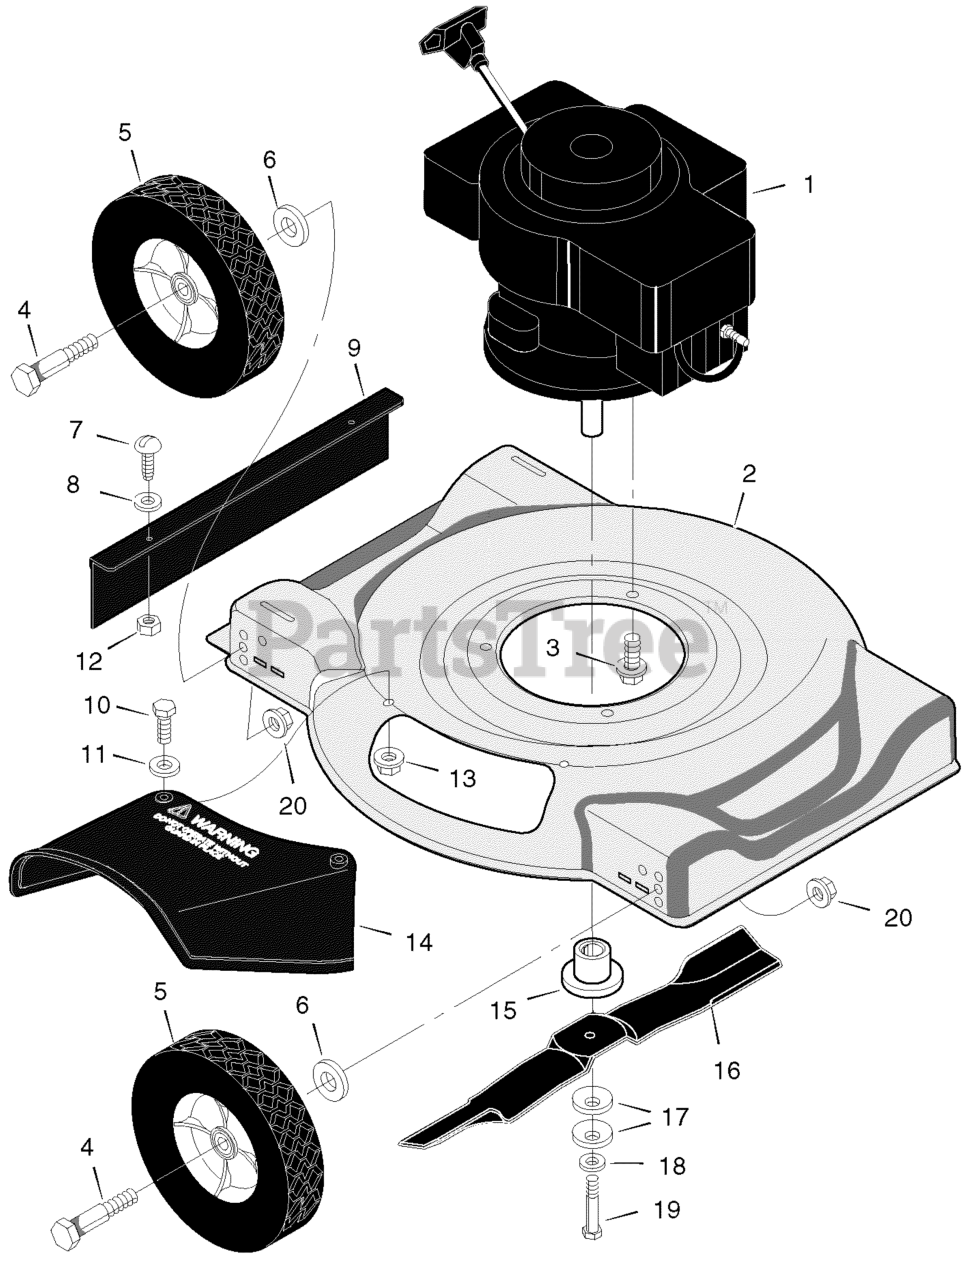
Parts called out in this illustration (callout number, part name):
1	Engine, Briggs & Stratton *
2	Housing
3	Bolt, Engine
4	Bolt, Axle
5	Wheel and Tire
6	Washer
7	Screw
9	Deflector, Rear
11	Washer
13	Locknut
14	Deflector, Chute
15	Blade Adapter
16	Blade 20"
17	Washer, Blade
18	Washer
20	Locknut
